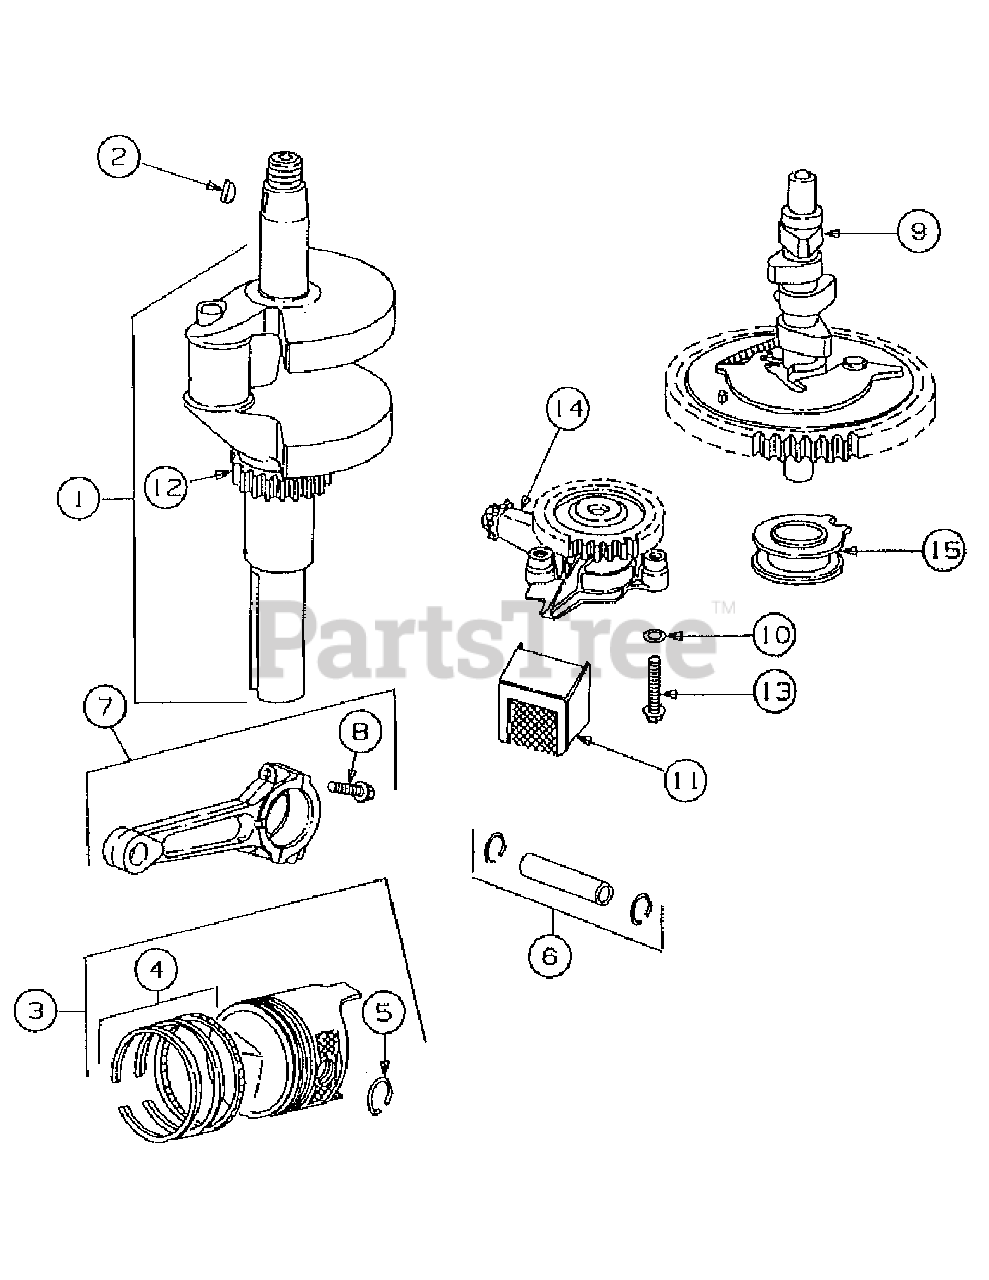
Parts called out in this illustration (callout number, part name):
1	Crankshaft
2	Key, Flywheel
3	Piston Assembly (Standard)
3	Piston Assembly (.010 Oversize)
3	Piston Assembly (.020 Oversize)
3	Piston Assembly (.030 Oversize)
4	Ring, Set Piston (Standard)
4	Ring, Set Piston (.010 Oversize)
4	Ring, Set Piston (.020 Oversize)
4	Ring, Set Piston (.030 Oversize)
5	Lock, Piston Pin
6	Pin Assembly, Piston (Standard)
7	Rod Assembly, Connecting
7	Rod, Connecting (.020 Undersize Crankpin Bore)
8	Screw, Connecting Rod
9	Gear, Cam
10	O-Ring (Oil Pump)
11	Screen, Oil
12	Gear, Timing
12	Key, Timing Gear
13	Screw, Sem
14	Oil Pump Assembly
15	Slider, Governor
